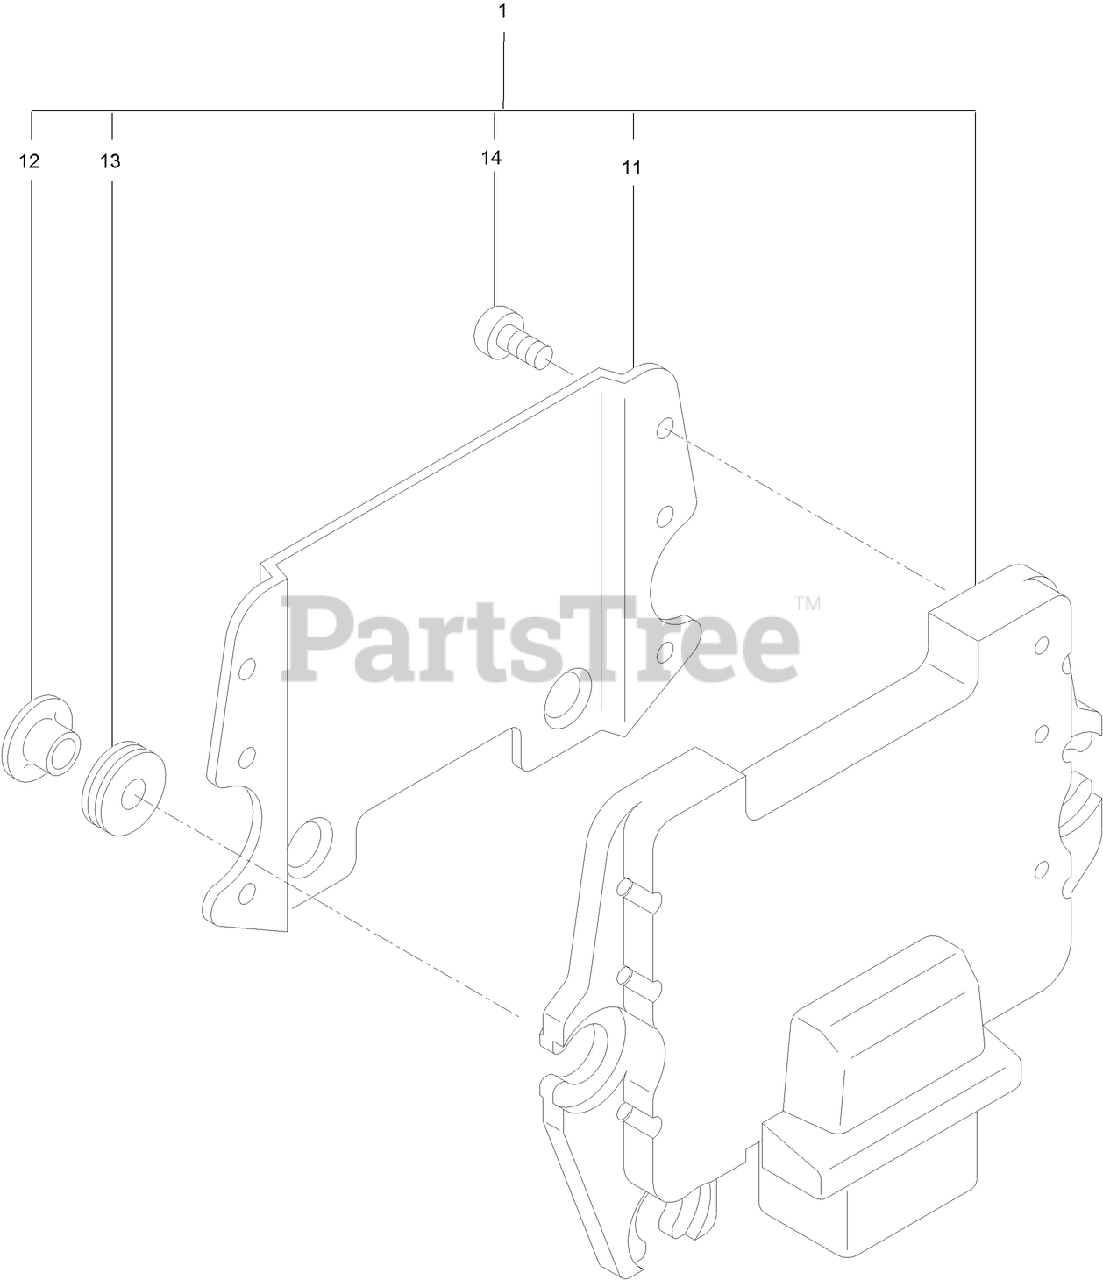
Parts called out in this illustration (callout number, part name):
1	SEE 135-4281 (SERVICE ASM)
11	SHIELD
12	COLLAR
13	ABSORBER
